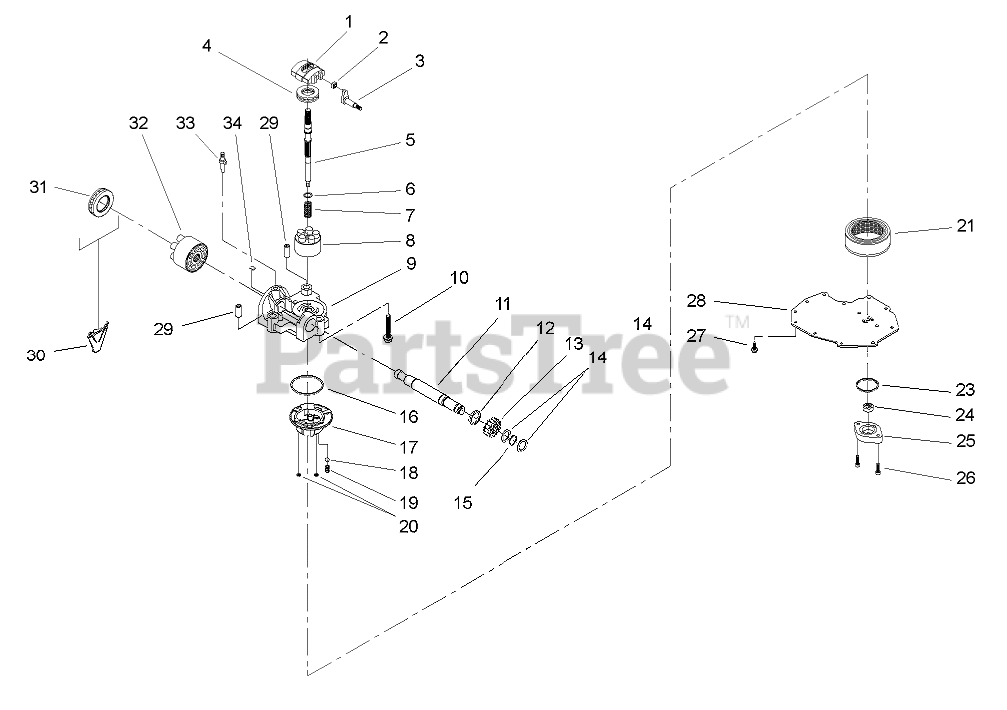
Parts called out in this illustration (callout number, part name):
1	SWASHPLATE-VARIABLE
2	GUIDE-SLOT
3	TRUNNION ASM
4	BEARING-THRUST
5	SHAFT-INPUT
6	WASHER-THRUST
7	SPRING-BLOCK
8	CYLINDER BLOCK ASM
9	CENTER SECTION KIT
11	SHAFT-OUTPUT
12	SPACER
13	GEAR-PINION, 16T
14	WASHER
15	RING-RETAINING
16	O-RING
17	BEARING
18	BALL
19	SPRING-RELIEF
20	O-RING
21	FILTER
23	O-RING
24	GEROTOR ASM
25	COVER-GEROTOR
26	CAPSCREW
28	COVER-LOWER
30	RETAINER-BEARING, MOTOR
31	BEARING-THRUST
32	CYLINDER BLOCK ASM
33	ACTUATOR-BYPASS
34	PLATE-BYPASS
